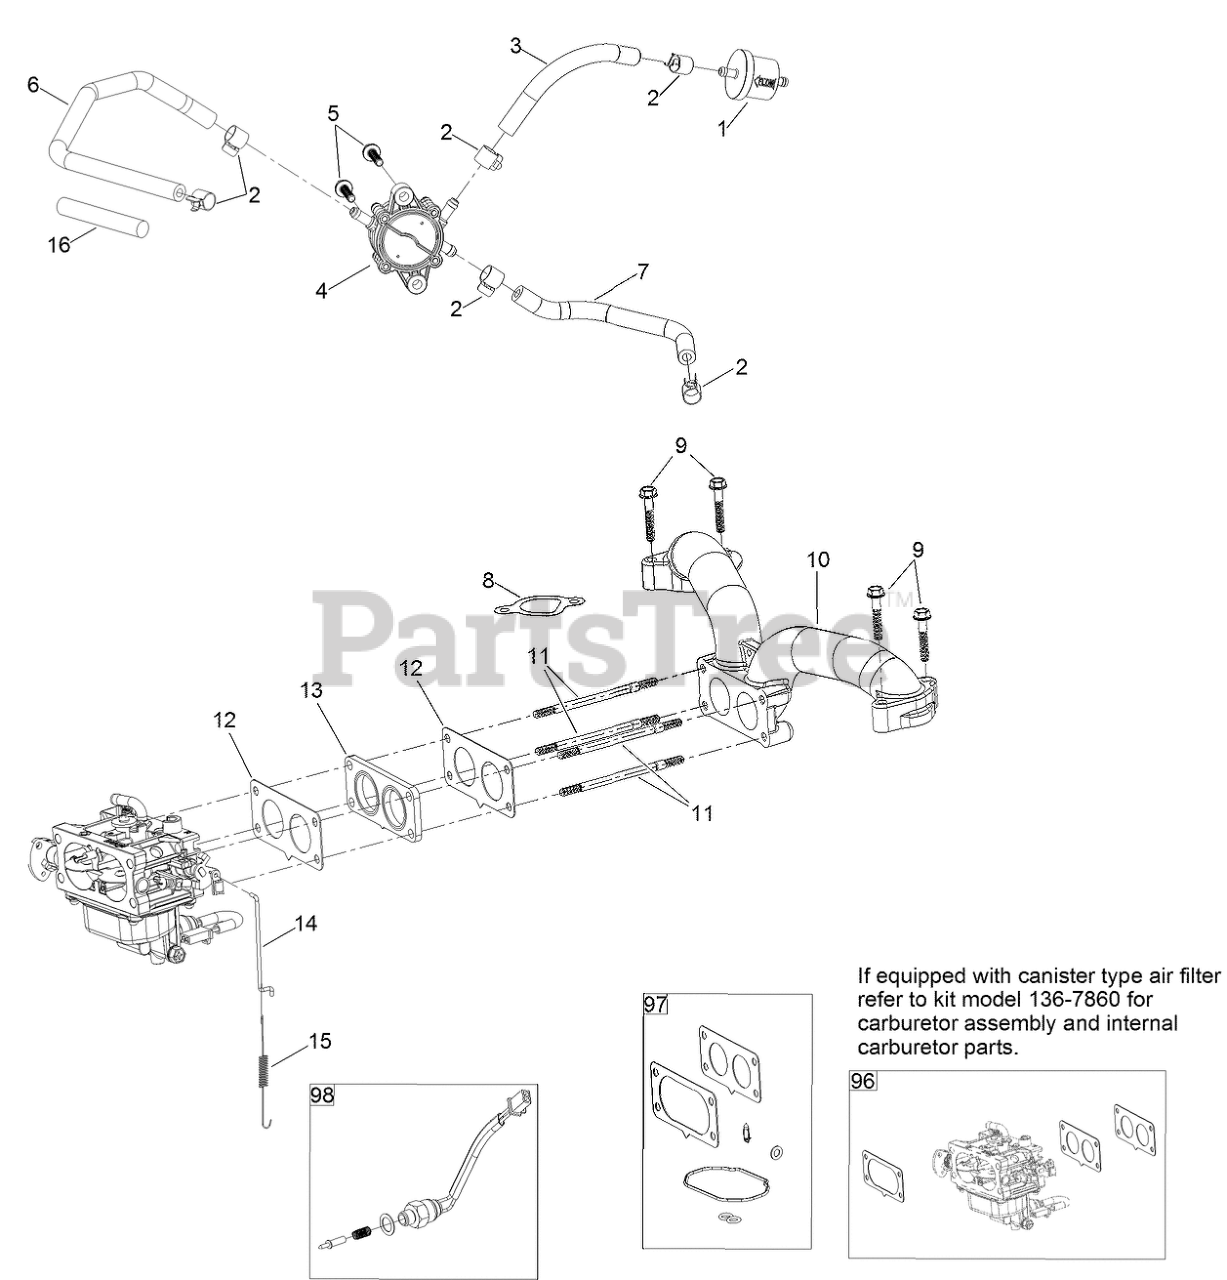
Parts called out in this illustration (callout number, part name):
1	FILTER-FUEL
2	CLAMP-FUEL LINE
3	LINE-FUEL
4	PUMP-FUEL
5	SCREW-HHF
6	HOSE-FUEL
7	HOSE-FUEL
8	GASKET-INTAKE
9	SCREW-HHF
10	MANIFOLD-INTAKE
12	GASKET-CARBURETOR
13	INSULATOR-CARBURETOR
14	LINKAGE-THROTTLE
15	SPRING-RETURN, THROTTLE
16	SLEEVE-FUEL LINE PROTECTOR
96	CARBURETOR REPLACEMENT KIT
97	CARBURETOR REPAIR KIT
98	SOLENOID KIT
